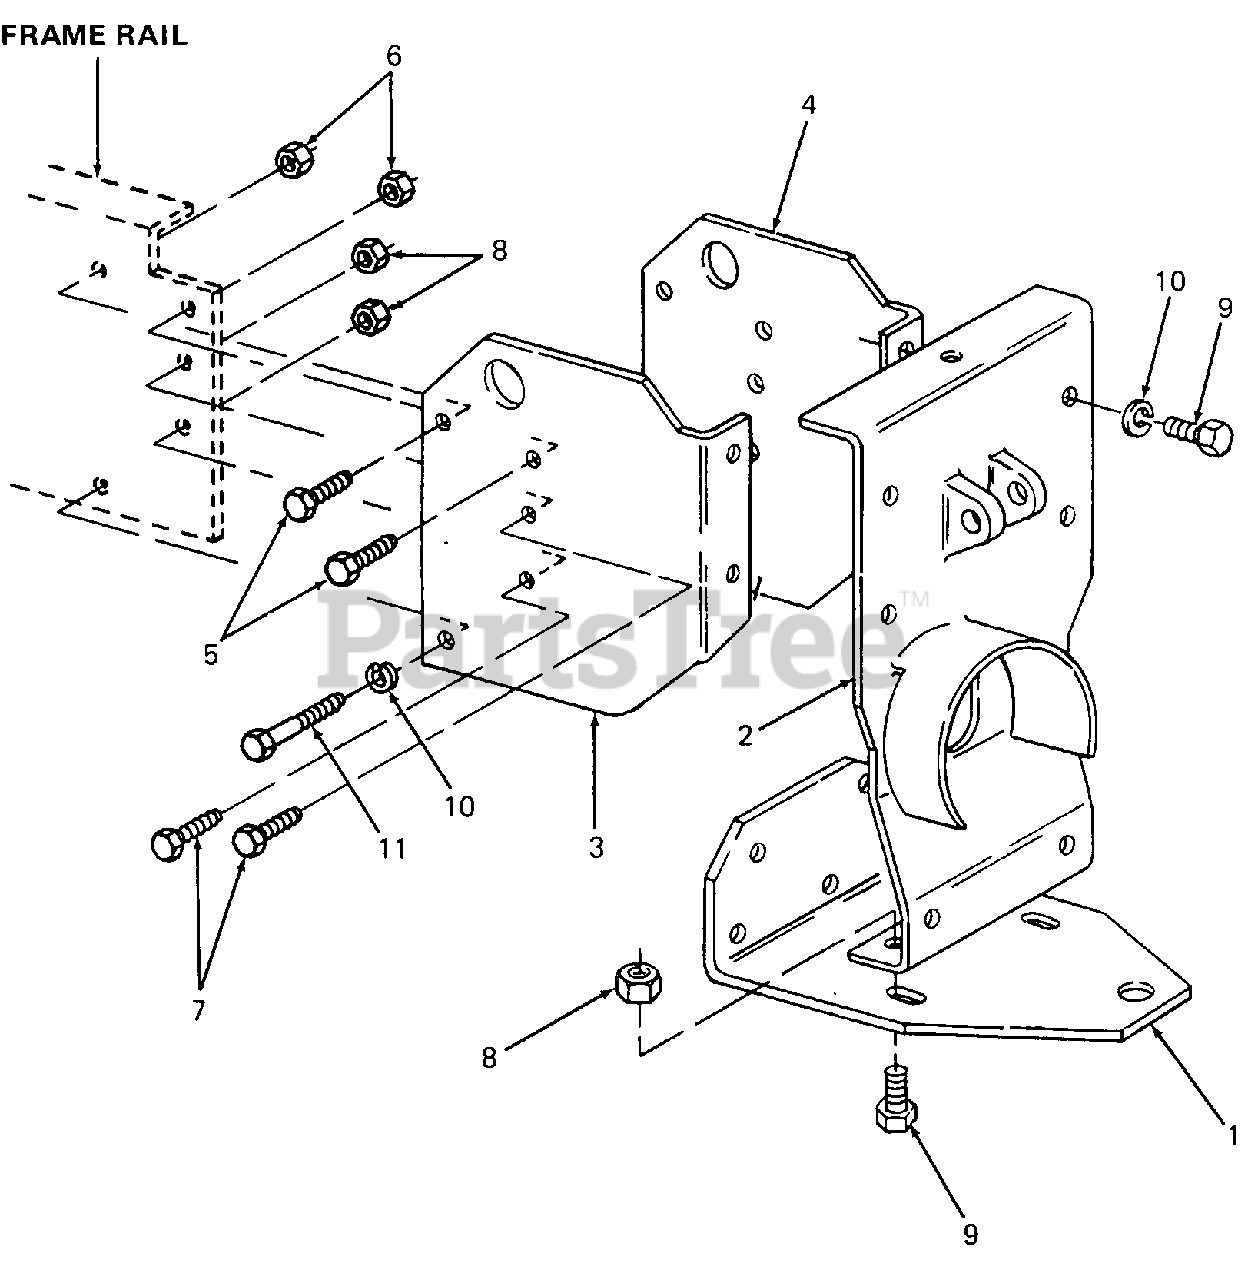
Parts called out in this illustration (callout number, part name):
1	Tow Plate
2	Drawbar Support Plate Assy
5	Screw, Hex Cap, 7/16-14 X .75 Lg GR5
6	Nut, Hex Center Lock, 7/16-14
7	Screw, Hex Cap, 3/8-16 X .75 Lg GR8
8	Nut, Hex Center Lock, 3/8-16 GR5
9	Screw, Hex Cap, 3/8-16 X 1.0 Lg GR5
10	Washer, Lock, 3/8
11	Bolt, Hex Patch, 3/8-16 X 3.25 Lg GR8
